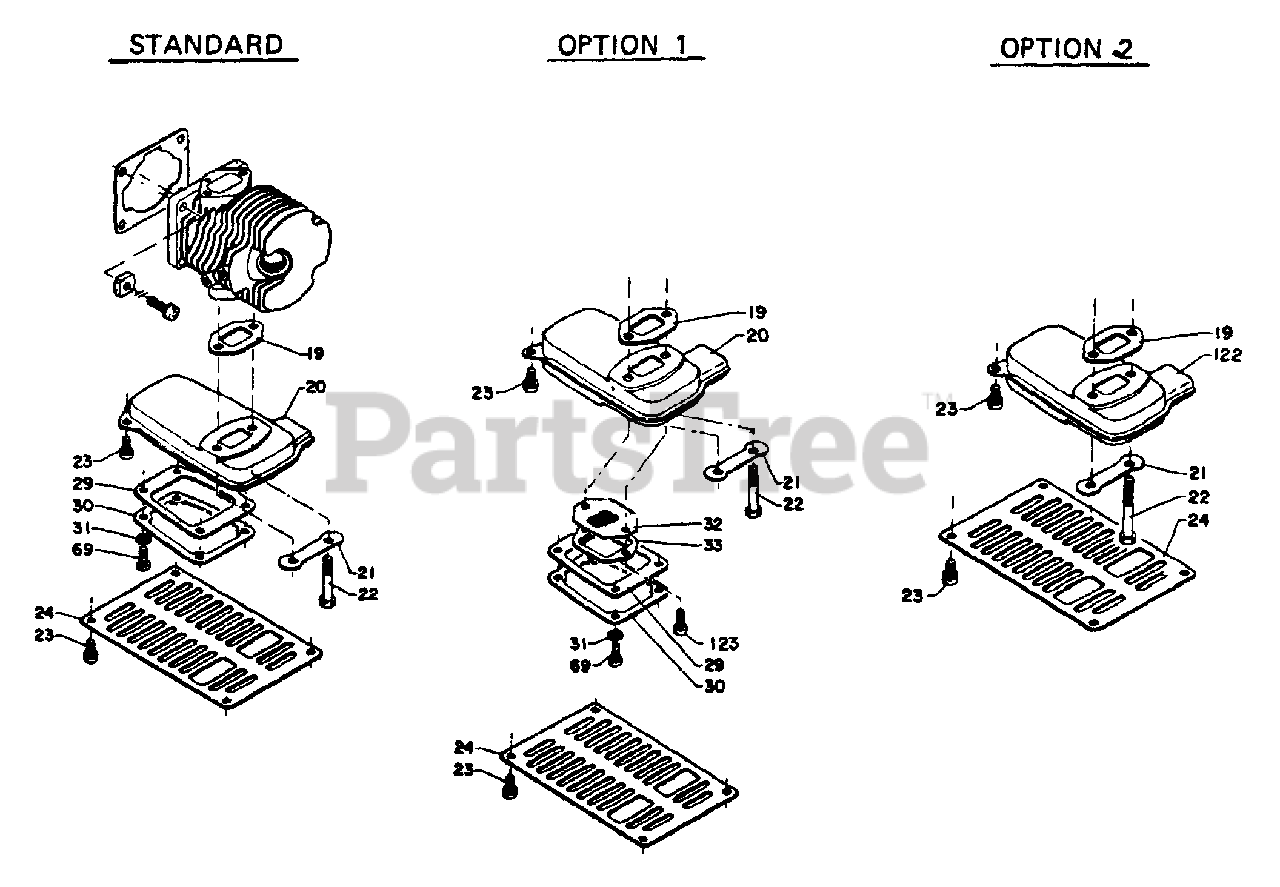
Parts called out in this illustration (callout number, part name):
19	GASKET, EXHAUST
20	CASE, MUFFLER
21	WASHER
22	BOLT 5×30
23	SCREW - 4×10
24	COVER, MUFFLER
29	GASKET, EXHAUST
30	LID, MUFFLER
31	WASHER, LOCK 4 MM
32	SCREEN, SPARK ARRESTER
33	RETAINER, SCREEN
69	SCREW 4×10
122	MUFFLER
123	SCREW 4 X 8
